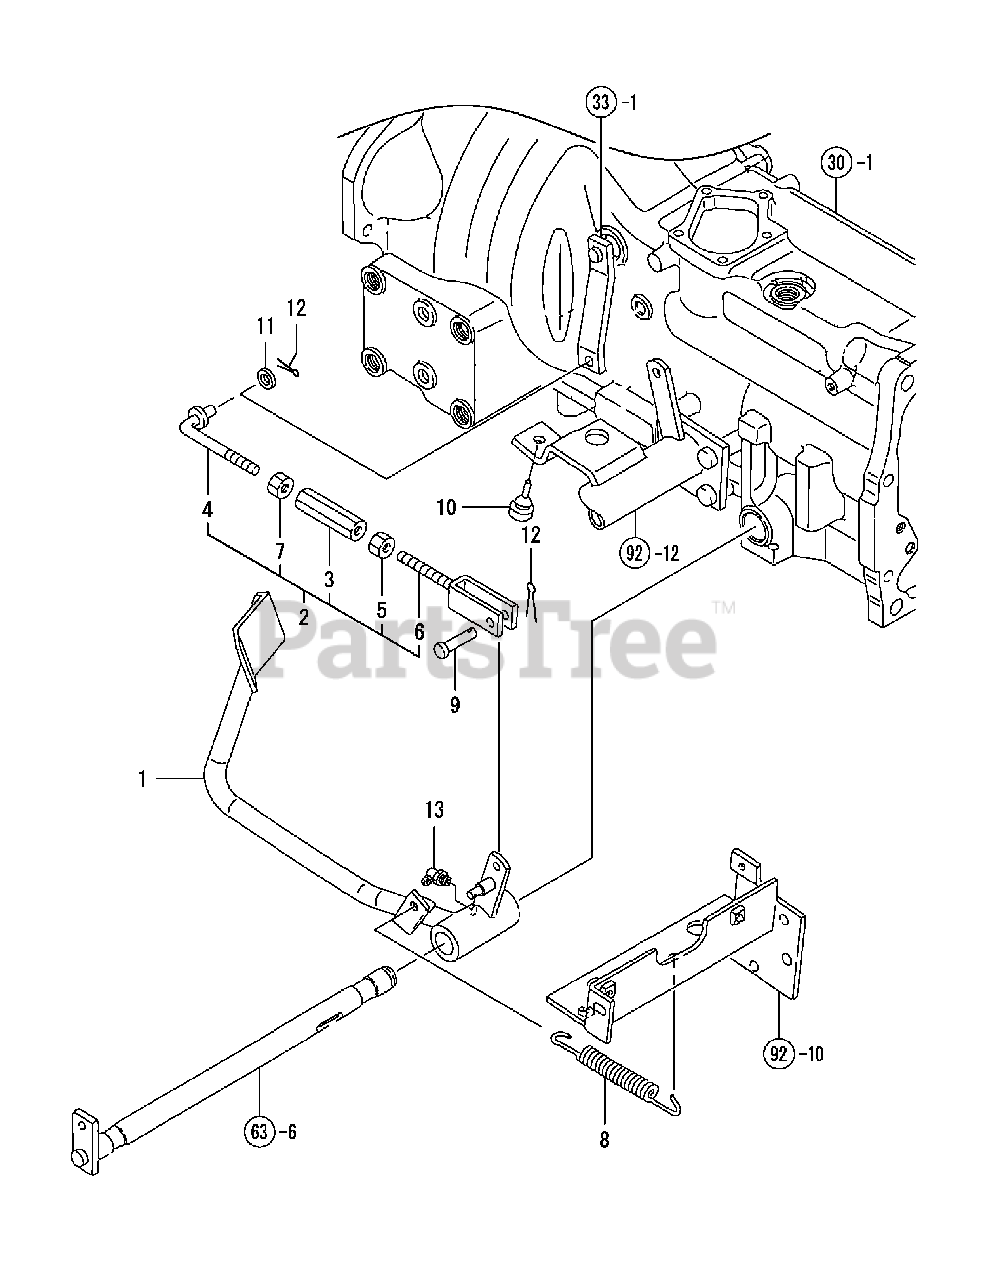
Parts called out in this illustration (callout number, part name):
2	ROD KIT,CLUTCH
3	TURNBUCKLE M10
6	ROD L.H.CLUTCH
8	SPRING, RETURN
10	STOPPER, PEDAL
11	WASHER 10,POLISHED
12	COTTER PIN 2.5X30
13	NIPPLE B,GREASE
